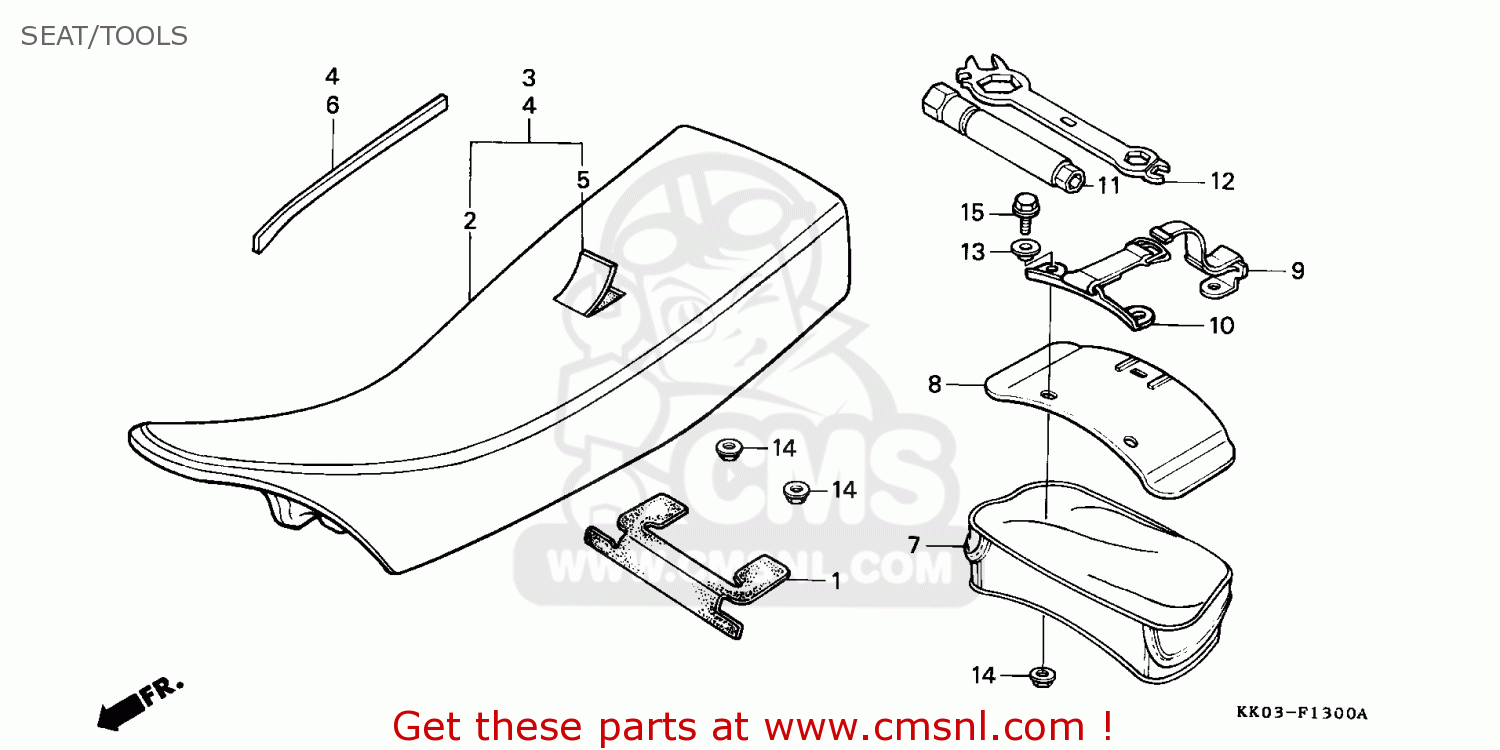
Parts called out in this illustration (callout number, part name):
1	RUB,SEAT UNDER
4	SEAT ASSY.
5	COVER, SEAT
6	TAPE
7	BAG COMP.,TAIL
8	PLATE,TAIL BAG BO
9	BAND B,CARRIER
10	BAND A.CARRIER
13	BRACKET,WASHER
15	BOLT,FLANGE,6X16
